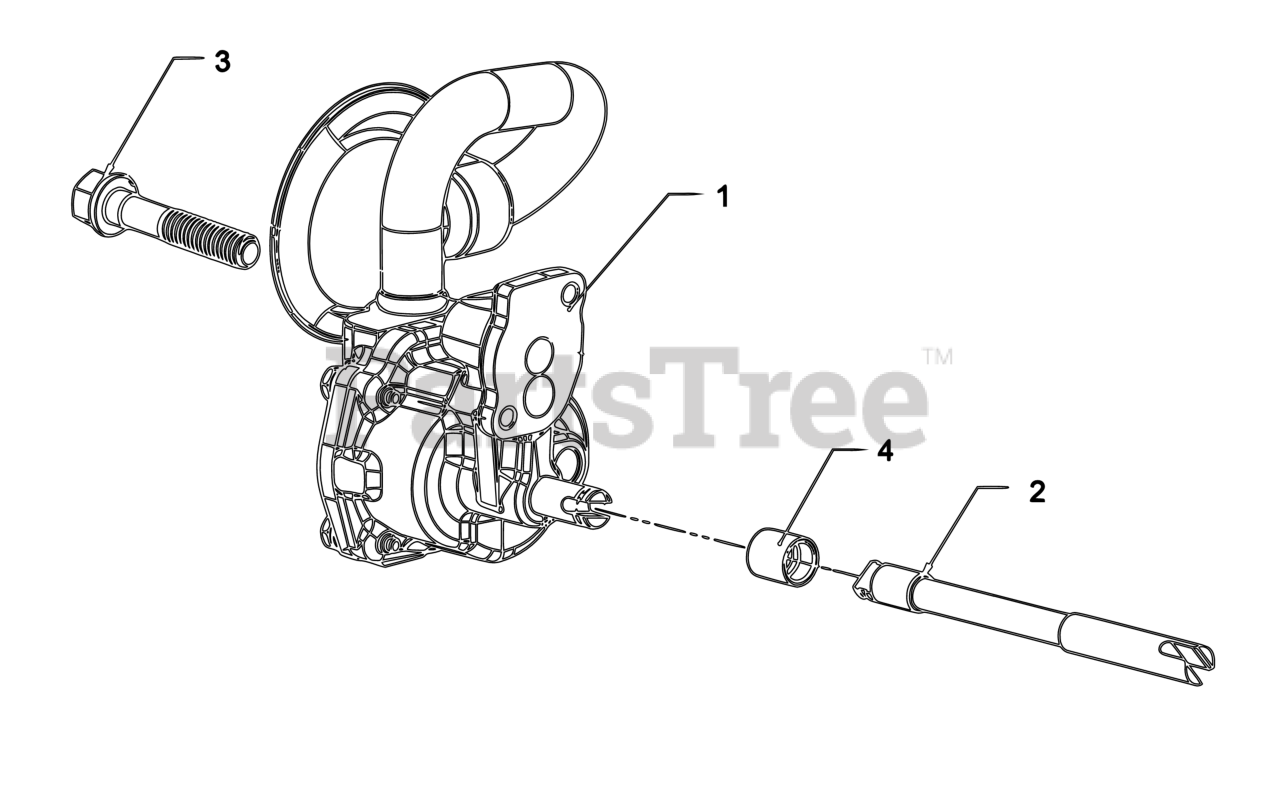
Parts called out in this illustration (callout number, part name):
1	PUMP, Oil
2	*SHAFT, OIL PUMP DRIVE
3	*BOLT, OIL PUMP
4	*RETAINER, OIL PUMP SHAFT
